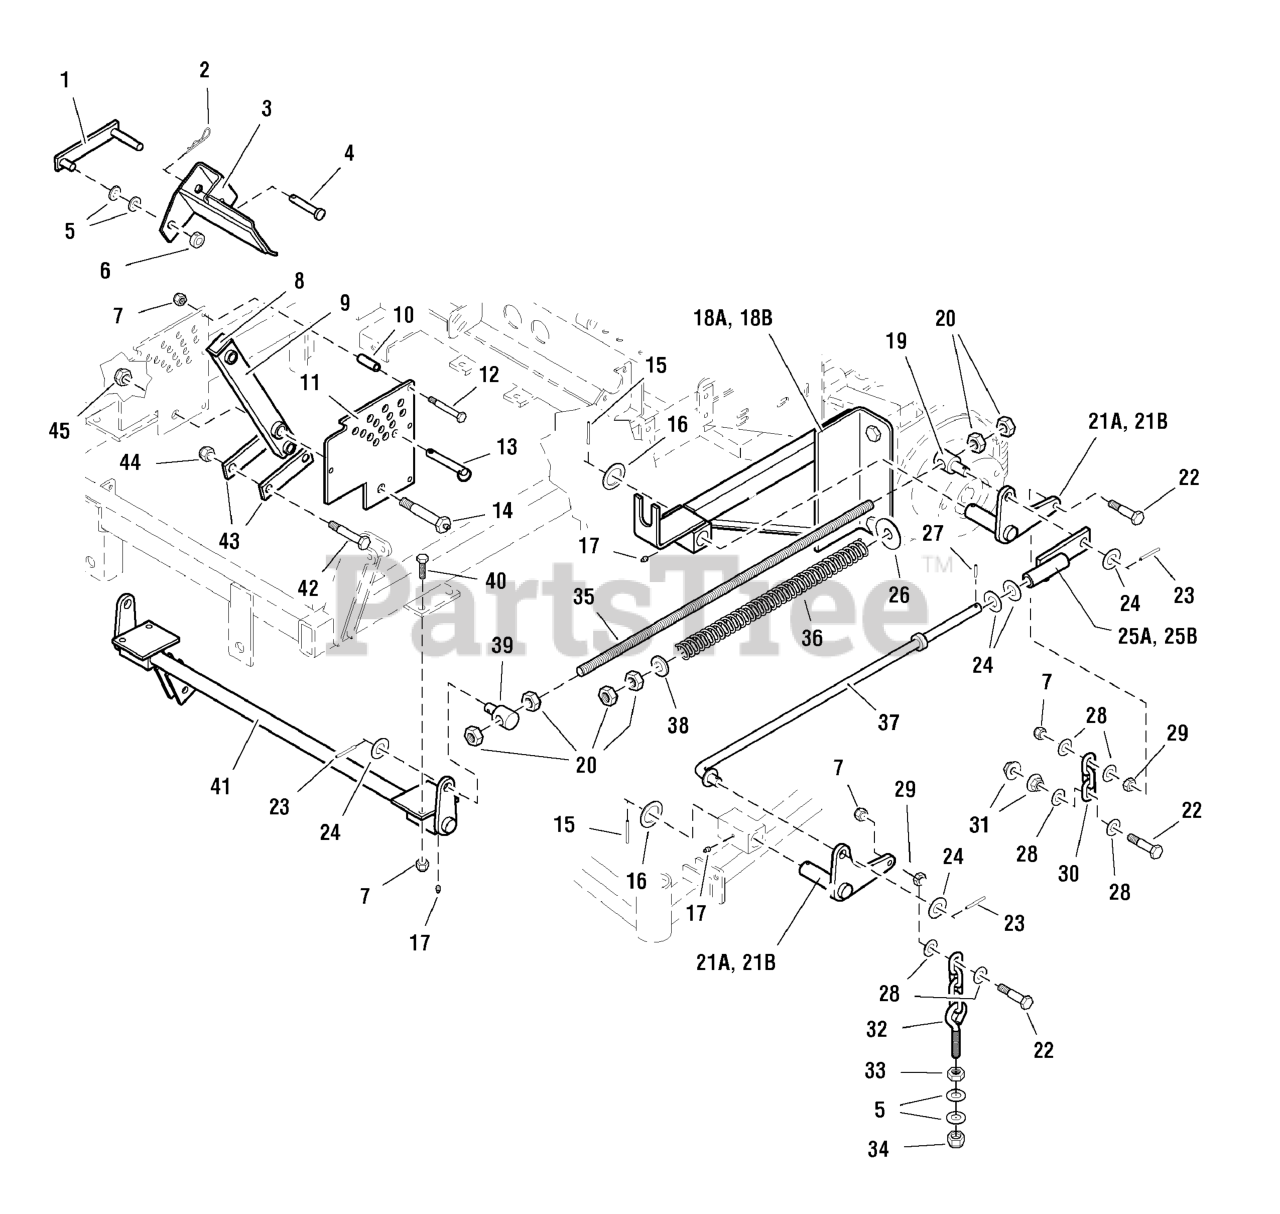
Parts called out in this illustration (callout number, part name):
1	DECK LIFT LOCK
2	HAIRPIN CLIP
3	WELD, DECK LIFT PEDAL
3	PEDAL SAFETY WALK
4	PIN, Clevis, 1/2 x 2-1/2
5	WASHER, 1/2 SAE
6	COLLAR, Split, 1/2
7	NUT, 3/8-16 HEX NYLON LOCK
9	ARM, Deck Lift Pivot
10	SPACER, .38 x .50 x 1.56
11	DECK HEIGHT PLATE
11	DECAL, Deck Height
12	BOLT, 3/8-16 X 2-3/4" GD5 CZ
13	PIN, 1/2 x 3
14	LIFT PIVOT BOLT
15	PIN, Roll, 3/16 x 1-1/2
17	GREASE FITTING
18A	REAR DECK LIFT FRAME - LH
19	SPRING ROD PIVOT
20	NUT, 5/8-11 Hex
21A	DECK LIFT PIVOT - LH
22	BOLT, 3/8-16 X 1-3/4" GD5 CZ
23	PIN, Spring, 3/16 x 1-1/4
24	WASHER, 5/8" SAE
25A	DECK LIFT LINK - LH
26	WASHER, 5/8" USS
27	PIN, Roll, 3/16 x 3/4
28	WASHER, 3/8 SAE
29	NUT, 3/8-16 HEX JAM
30	CHAIN, 3 LINKS
31	NUT, 3/8-16 Hex Serrated Flange
32	HANGER, FRONT DECK - 4 LINK, 5.5" EB
33	NUT, 1/2-13 Hex
34	NUT, 1/2-13 HEX NYLON LOCK
35	SPRING ROD
36	SPRING, Deck Lift
37	DECK LIFT ROD
38	SPACER, .63 x 1.06 x .23
39	SPRING ROD PIVOT
40	BOLT, 3/8-16 X 1-1/4" GD5 CZ
41	DECK LIFT SHAFT & MOUNT ASSEMBLY
42	BOLT, 1/2-20 x 3
43	DECK LIFT LINK
44	NUT, Hex, Nylon Lock, 1/2-20
45	NUT, 5/8-11 Hex Jam Nylon Lock
